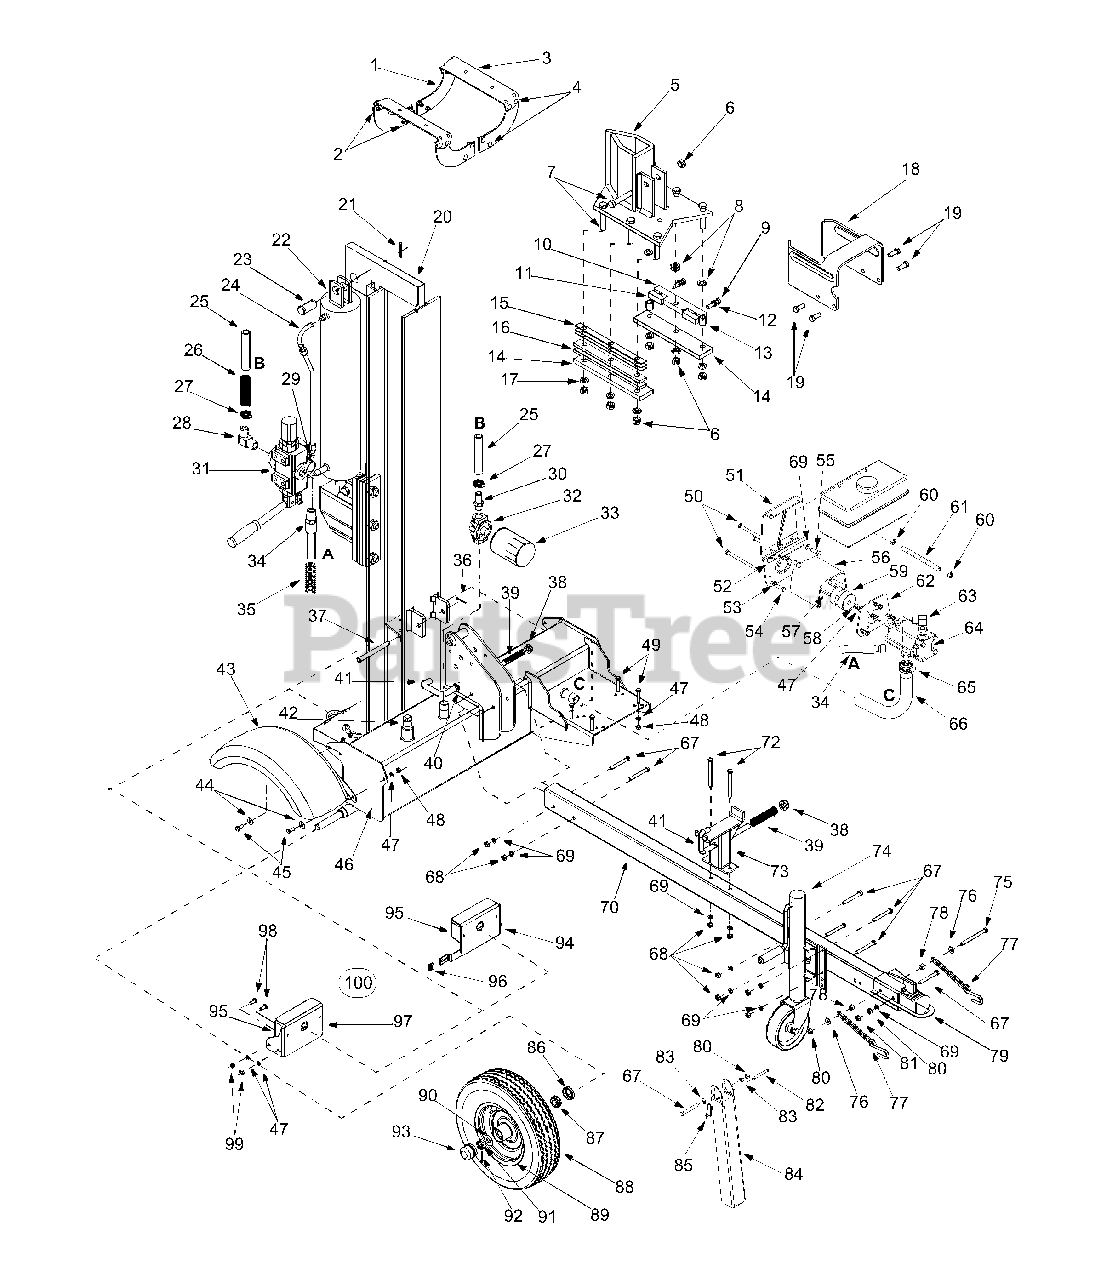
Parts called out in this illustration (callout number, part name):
4	Carriage Bolt 3/8-16 x 1.0
6	Lock Nut 1/2-20
7	Hex Cap Screw 1/2-20 x 2.75
8	Flat Washer .531 ID x .93 OD
9	Hex Cap Screw 3/8-24 x 1.5
12	Hex Jam Nut 3/8-24
13	Spacer
17	Lock Washer 1/2
19	Hex Cap Screw 3/8-16 x 1.0
22	Kit Seal 5.0" for Best Metals cylinder 718-0313
22	Hydraulic Cylinder
22	Kit Seal 5.0" for XINGHUI cylinder 718-0313A
22	Kit Seal 5.0" for ENERGY cylinder 718-0313A
23	Clevis Pin
24	Hydraulic Tube
25	Return Hose 3/4" ID x 44" Lg.
26	Hose Guard
27	Hose Clamp 5/8"
28	Return Elbow
29	90 Degree Solid Male Adapter
30	3/4" Hose Adapter
32	Filter Housing
33	Oil Filter
34	High Pressure Hydraulic Hose
35	Hose Guard
36	Cotter Pin 1/8"
37	Hinge Pin 1/2 x 4.8" Lg.
38	Push Cap
39	Compression Spring 4"
40	Flat Washer .635 ID x .93 OD
41	Locking Rod
42	Pipe Plug
45	Hex Cap Screw 5/16-24 x .75
46	Frame Assembly 7.0 Gal
47	Lock Washer 5/16
48	Hex Nut 5/16-24
49	Hex Cap Screw 5/16-24 x 1.
50	Hex Cap Screw 5/16-24 x 5.
51	Fuel Tank Mounting Bracket
52	Fuel Tank Mounting Bracket
53	Lock Washer 3/8
54	Hex Cap Screw 5/16-24 x 1.0
55	Hex Cap Screw 3/8-16 x 1.0
56	Shoulder Spacer
57	Key 1/4" x 2.00"
57	Key 3/16" x .75"
58	Hex Screw 5/16
59	Flexible Coupling 1.00 x .437
60	Hose Clamp
61	Fuel Line Hose
63	Adapter 7/8-14
64	Gear Pump (16 gmp)
64	Pump Kit
64	Gear Pump (15 gpm)
65	Hose Clamp
66	Suction Hose
67	Hex Cap Screw 3/8-16 x 3.0
68	Hex Nut 3/8-16
69	Lock Washer 3/8
72	Hex Cap Screw 3/8-16 x 4.0
75	Hex Cap Screw 3/8-16 x 4.25
76	Flat Washer .385 ID x .870 OD
77	Chain
78	Spacer
79	Hitch Coupler
80	Lock Nut 3/8-16
81	Hex Jam Nut 3/8-16
82	Clevis Pin
83	Flat Washer
86	Bearing Seal
87	Bearing Cone
88	Wheel Assembly
89	Rim Assembly
90	Flat Washer .76" ID x 1.5" OD
91	Slotted Nut 3/4-16
92	Cotter Pin 5/32" x 1-1/4" Lg.
93	Hub Cap
96	Nut 1/4-20
99	Hex Nut 5/16-24
100	Taillight Kit (NLA)
